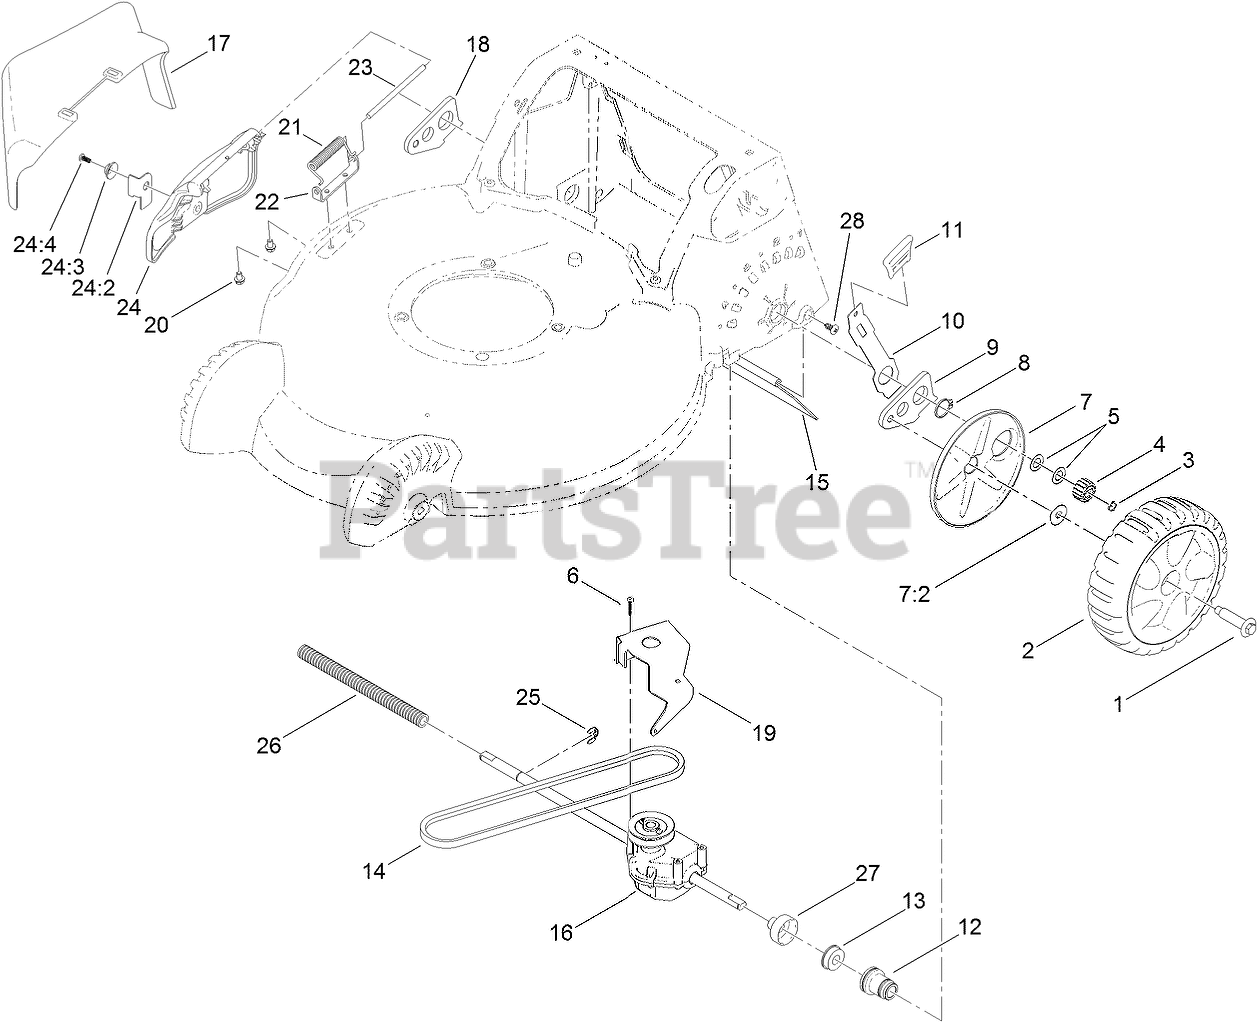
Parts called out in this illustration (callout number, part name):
1	BOLT-SHOULDER
2	REAR WHEEL ASM
3	RING-RETAINING
4	GEAR-PINION, 15T
5	WASHER-PLAIN
6	SCREW-PLASTITE
7	WHEEL COVER ASM
7:2	WASHER-STEPPED
8	RING-RETAINING
9	ARM-REAR PIVOT, LH
10	ARM-SPRING, REAR
11	KNOB-HOC
12	RETAINER-BEARING
13	BEARING-BALL
14	V-BELT
15	SHIELD-TRAILING
16	TRANSMISSION ASM
17	CHUTE-DISCHARGE, SIDE
18	ARM-REAR PIVOT, RH
19	BRACKET-TRANSMISSION
20	SCREW-HWH
21	SPRING-TORSION
22	BRACKET-COVER
23	ROD-COVER
24	DISCHARGE DOOR ASM
24:2	LATCH-DOOR
24:3	CAP-DOOR
24:4	SCREW-PLASTITE
25	RING-CLIP, LOCKING
26	CONDUIT-CONVOLUTED, SPLIT
27	CAP-BEARING
28	SCREW-PTH
